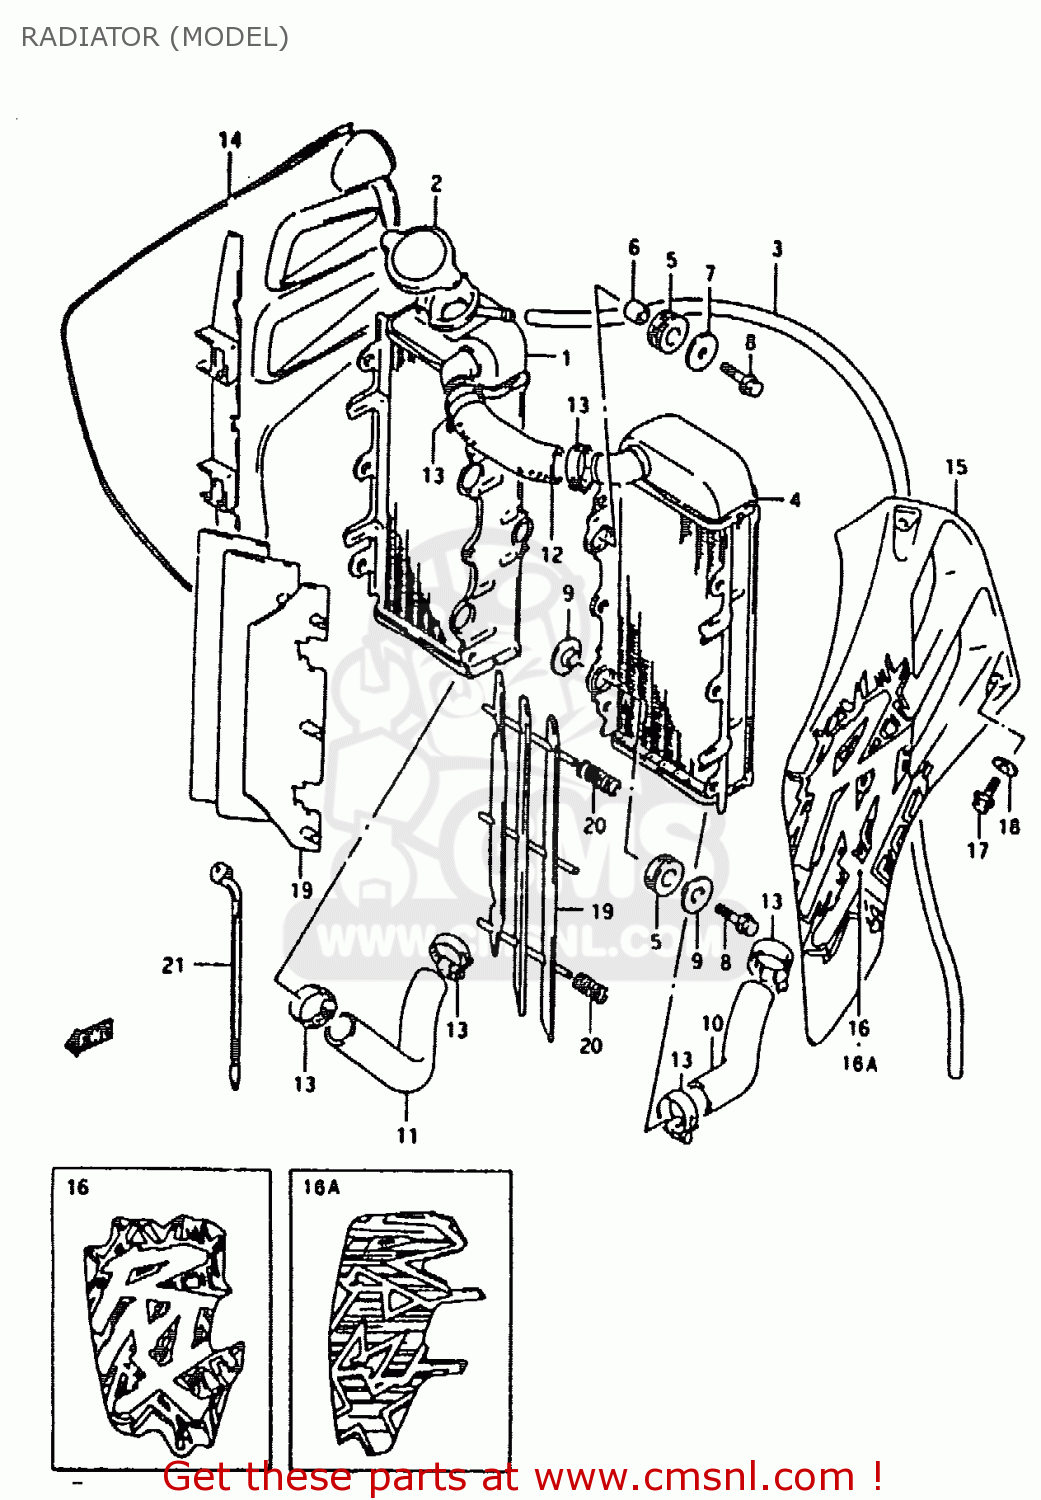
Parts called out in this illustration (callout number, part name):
1	RADIATOR,WATER,R
2	CAP,RADIATOR
3	HOSE(5X8X2000)
4	RADIATOR COMP,WATER,LEFT
5	CUSHION,RADIATOR LWR
6	SPACER(6.5X10.5X12)
7	WASHER (6.5X24X1.2)
8	SCREW
9	WASHER,RDTR SPRT
10	HOSE, INLET
11	HOSE,RADIATOR OUTLET
12	HOSE,RADIATOR JOINT NO.1
13	CLAMP
14	COVER, RADIATOR RH
15	COVER, RADIATOR LH
16	EMBLEM, RADIATOR COVER, RH
16A	TAPE,RADIATOR COVER,L
17	BOLT
18	BOLT
19	LOUVER,RADIATOR
20	SPRING
21	SPRING
22	CLAMP L:165
